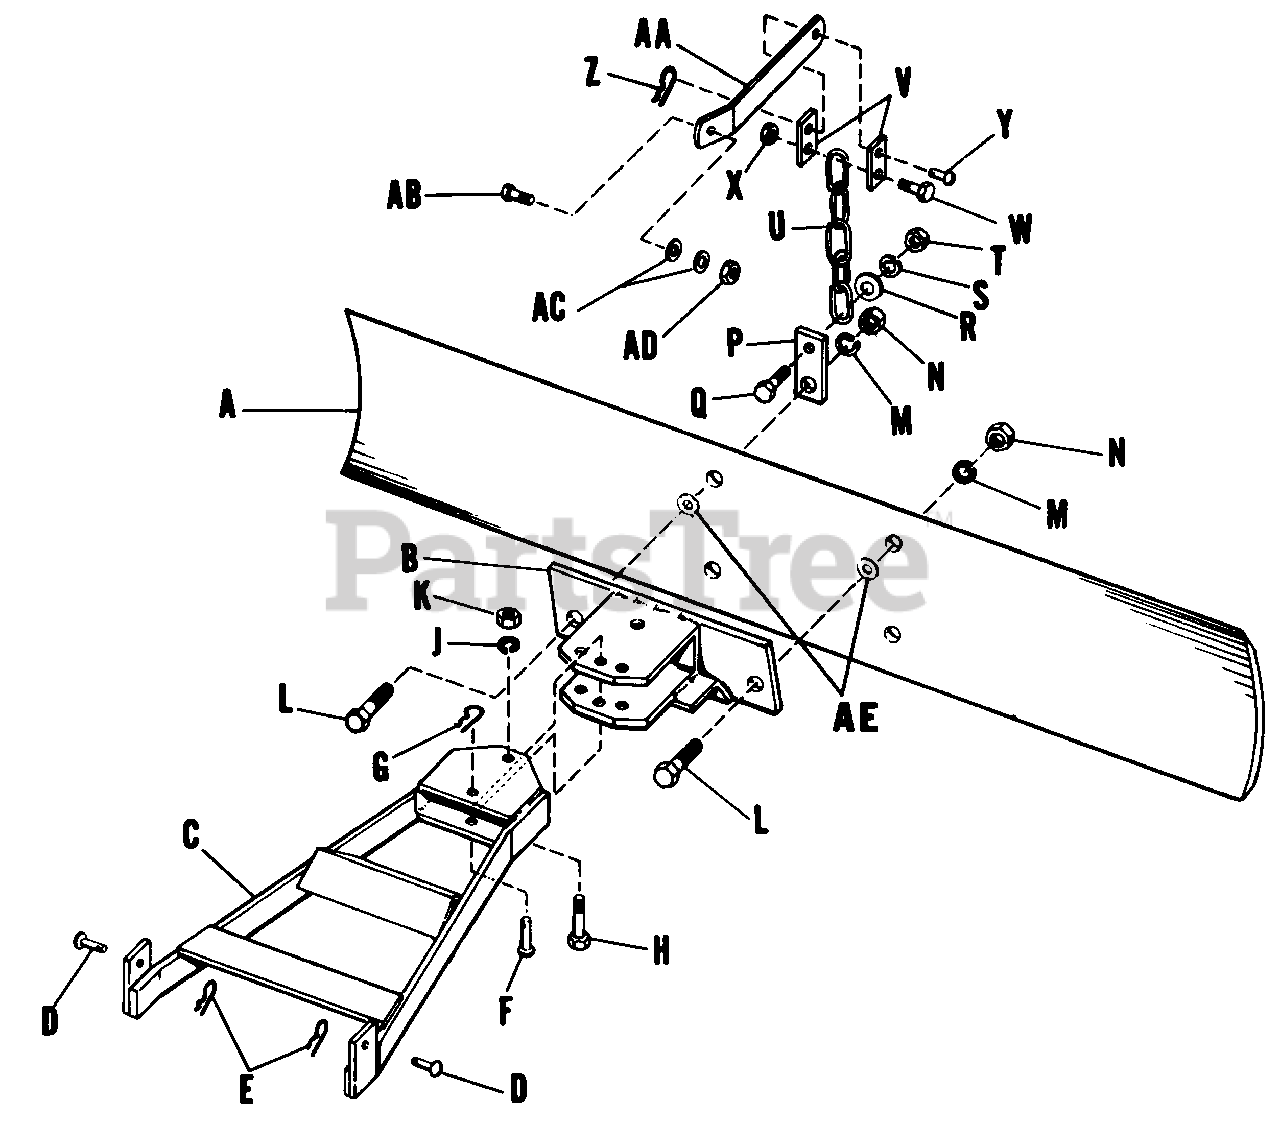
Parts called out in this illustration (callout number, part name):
A	Blade, Grader, 42"
B	Hitch Assembly
C	Draw Bar Assembly
D	Pin
E	Spring Clip
G	Spring Clip
H	Capscrew, Hex Head, 5/8"-11 NC x 3" lg .
J	Lockwasher, 5/8"
K	Nut, Hex, Full, 5/8"-11 NC
L	Capscrew, Hex Head, 5/8"-11 NC x 2" lg,
M	Lockwasher, 5/8"
N	Nut, Hex, Full, 5/8"-11 NC
Q	Capscrew, Hex Head, 3/8"-16 NC x 1 1/4" lg.
R	Plain Washer, 3/8"
S	Lock Washer, 3/8"
T	Nut, Hex, Full, 3/8"-16 NC
U	Chain
W	Capscrew, Hex Head, 3/8"-16 NC x 1 1/4" lg.
X	Nut, Hex, Full, Lock, 3/8"-16 NC
Z	Spring Clip
AB	Capscrew, Hex Head, 3/8"-16 NC x 1 1/4" lg.
AC	Plain Washer, 3/8"
AD	Nut, Hex, Full, Lock, 3/8"-16 NC
AE	Flat Washer, 1-1/16"
